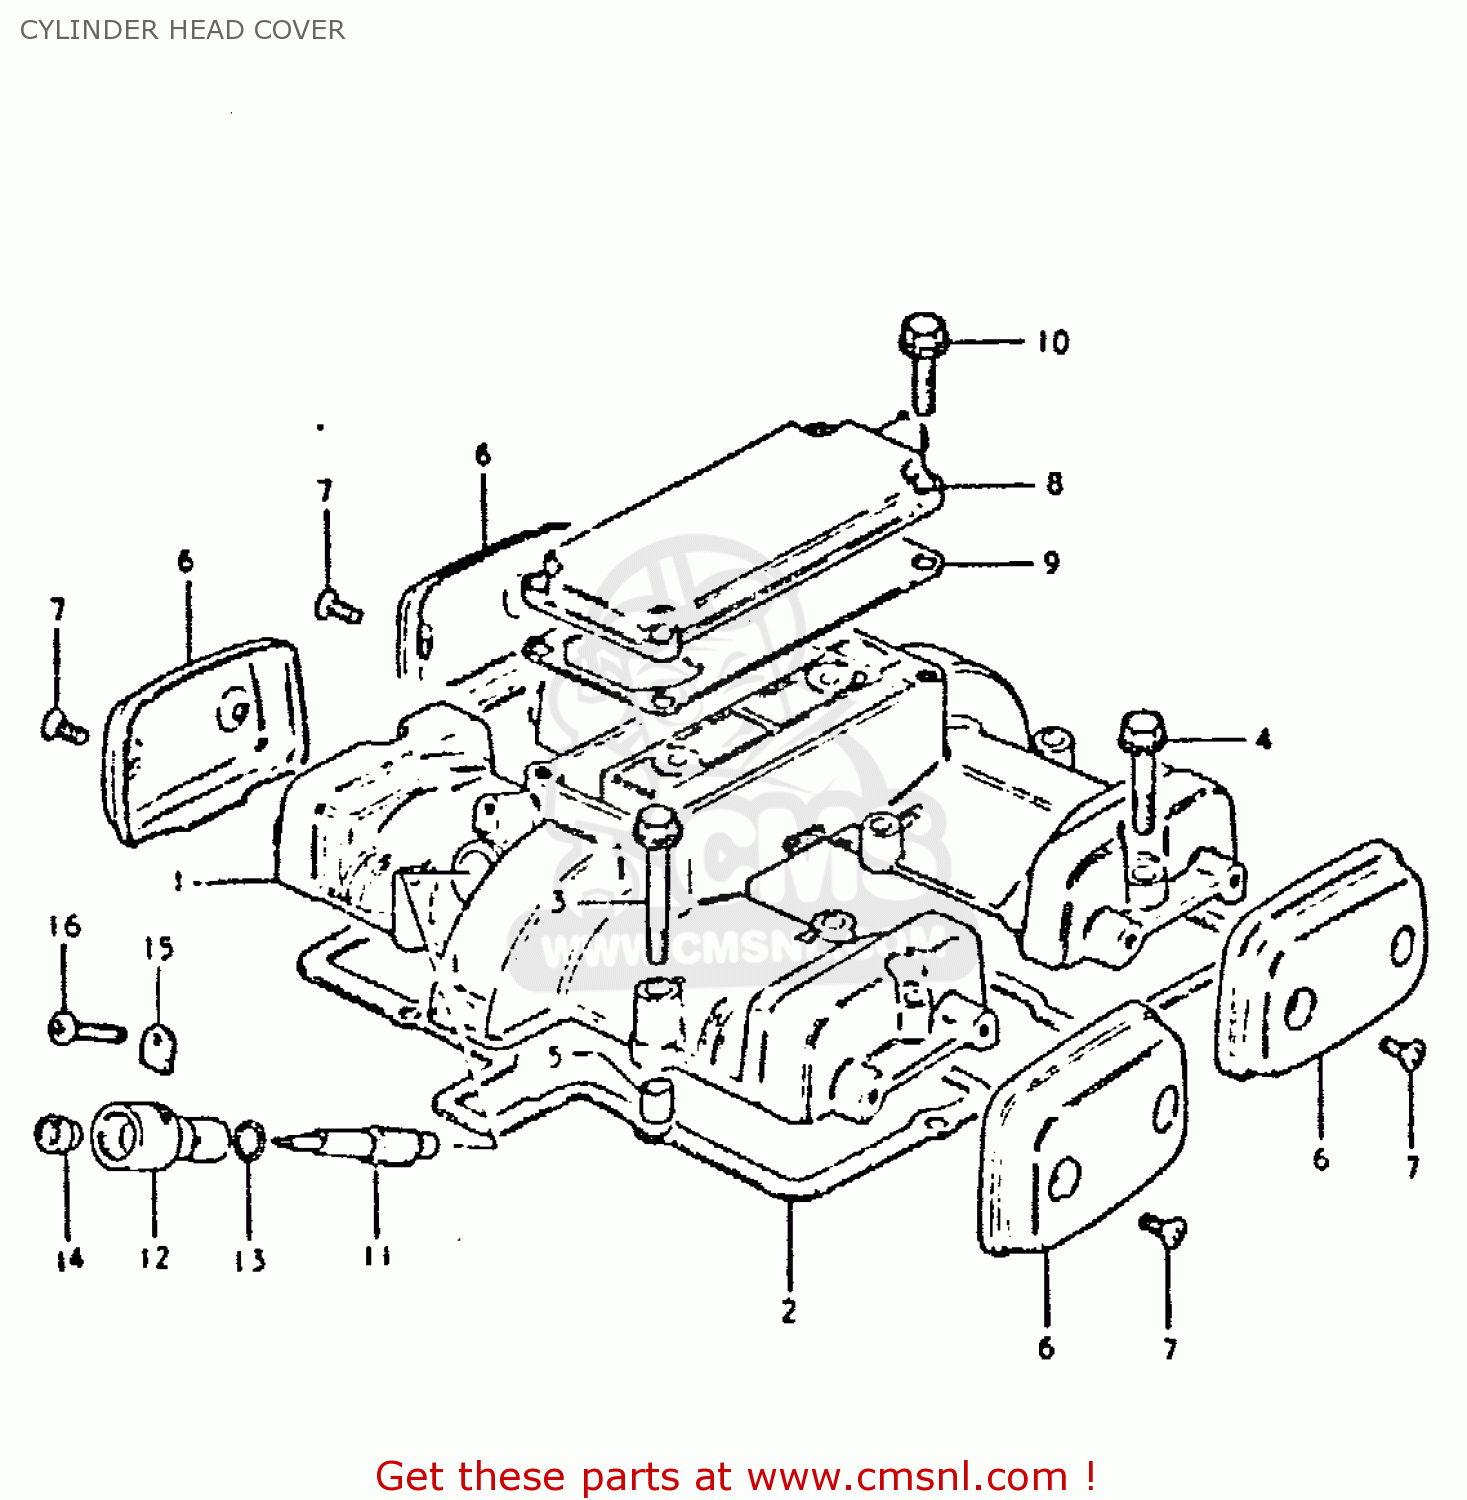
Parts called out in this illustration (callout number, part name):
1	COVER, CYLINDER HEAD
2	GASKET (MCA)
3	BOLT 6X35
4	BOLT
5	PIN(6.2X8X11)
6	CAP,CYLINDER HEAD COVER
7	SCREW 5X12
8	COVER,BREATHER
9	GASKET (MCA)
10	BOLT,REAR
11	GEAR,TACHOMETER DRIVEN
12	SLEEVE,TACHOMETER DRIVE
13	SEAL,TACHOMETER DRIVEN
14	SEAL,OIL(5X12X8)
15	PLATE,TACH DRIVE GEAR SLEEVE
16	SCREW(5X12)
